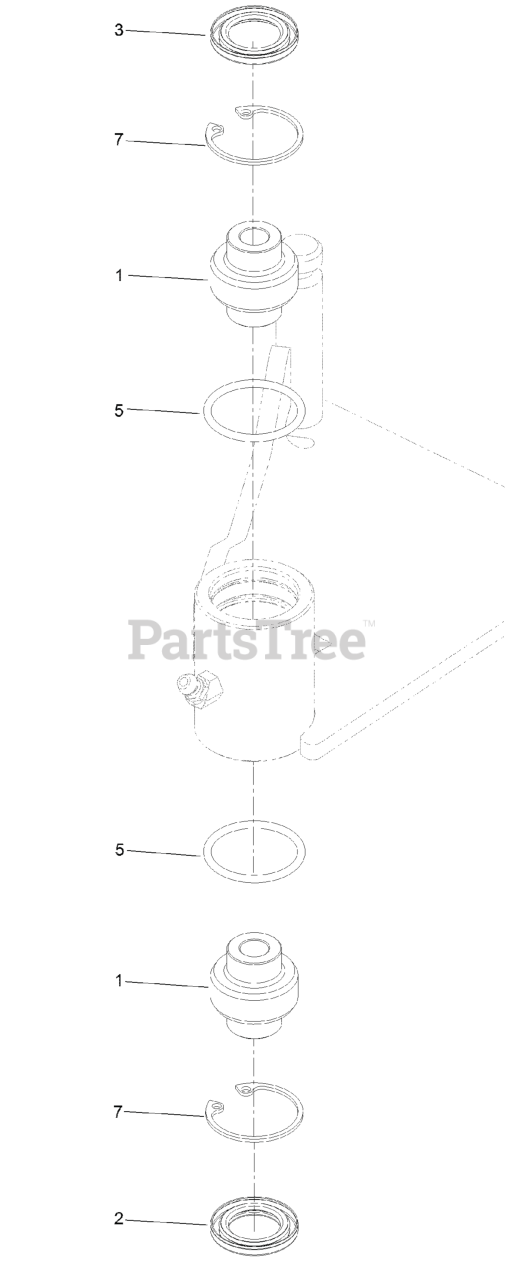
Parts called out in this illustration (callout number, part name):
1	BEARING-SPHERICAL
2	SEAL-LIP, DOUBLE
3	SEAL-LIP, SINGLE
7	RING-SNAP
